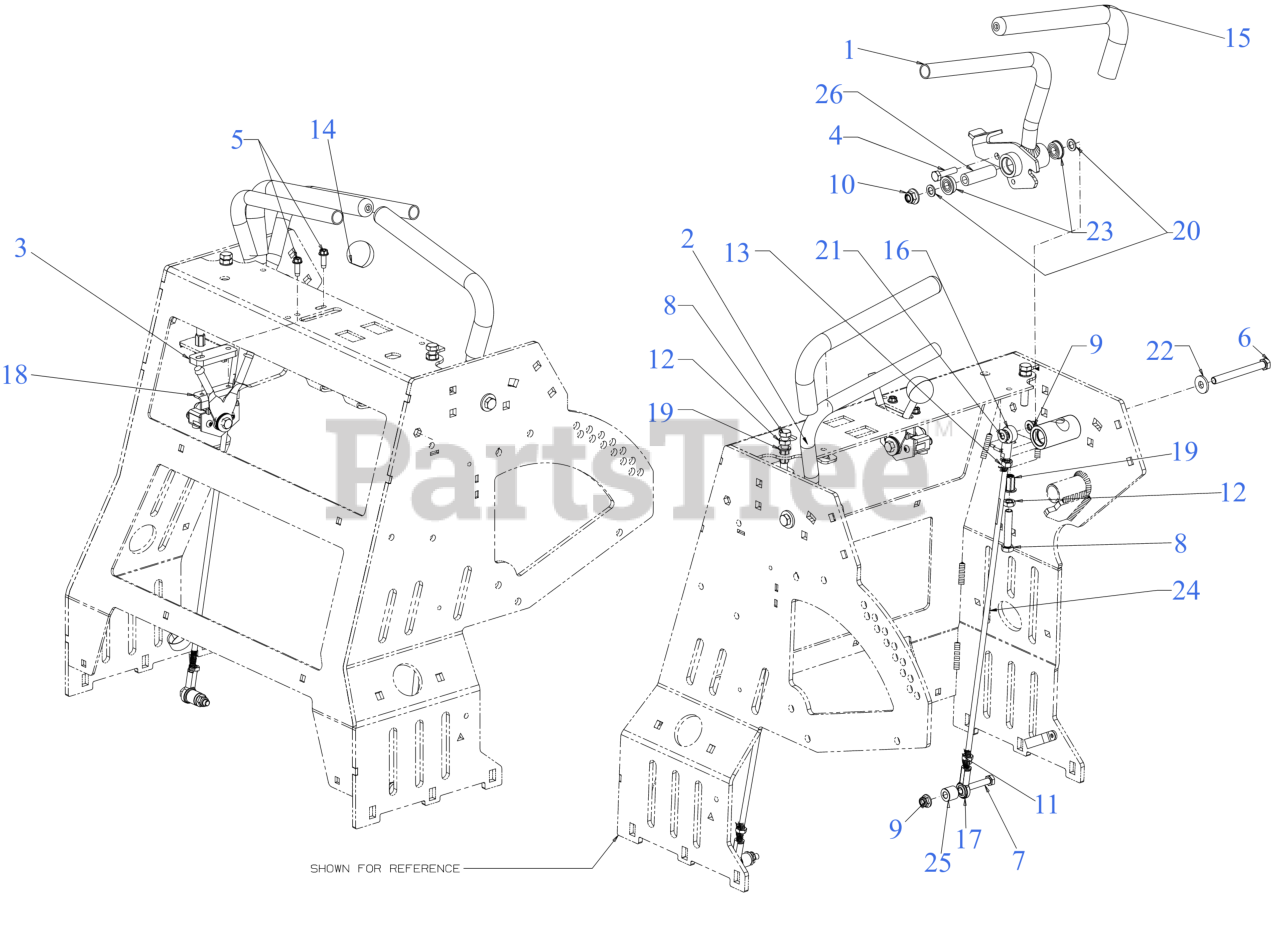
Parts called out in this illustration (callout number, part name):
1	CONTROL HANDLE (LH)
2	CONTROL HANDLE (RH)
4	SCREW 5/16-18 x 1.25 GR5
5	SCREW 1/4-20 x .750
6	SCREW 3/8-16 x 3.50 GR5
7	SCREW 5/16-18 x 1.75 GR5
8	SCREW 3/8-16 x 2 GR5
9	FLANGE LOCK NUT 5/16-18
11	HEX JAM NUT 5/16-24 GR5
13	NUT-5/16X 24
15	GRIP .75 ID X 1.00 OD
16	ROD END 5/16 ID
17	END ROD- 5/16 (LH)
18	ELECTRONIC THROTTLE CONTROL
19	RIV NUT 3/8-16
20	FLAT WASHER
21	FLAT WASHER
23	FLANGE BEARING
24	CONTROL ROD
25	SPACER .34 x .75 x .63 LG
26	SPACER .379 x .63 x 1.957
